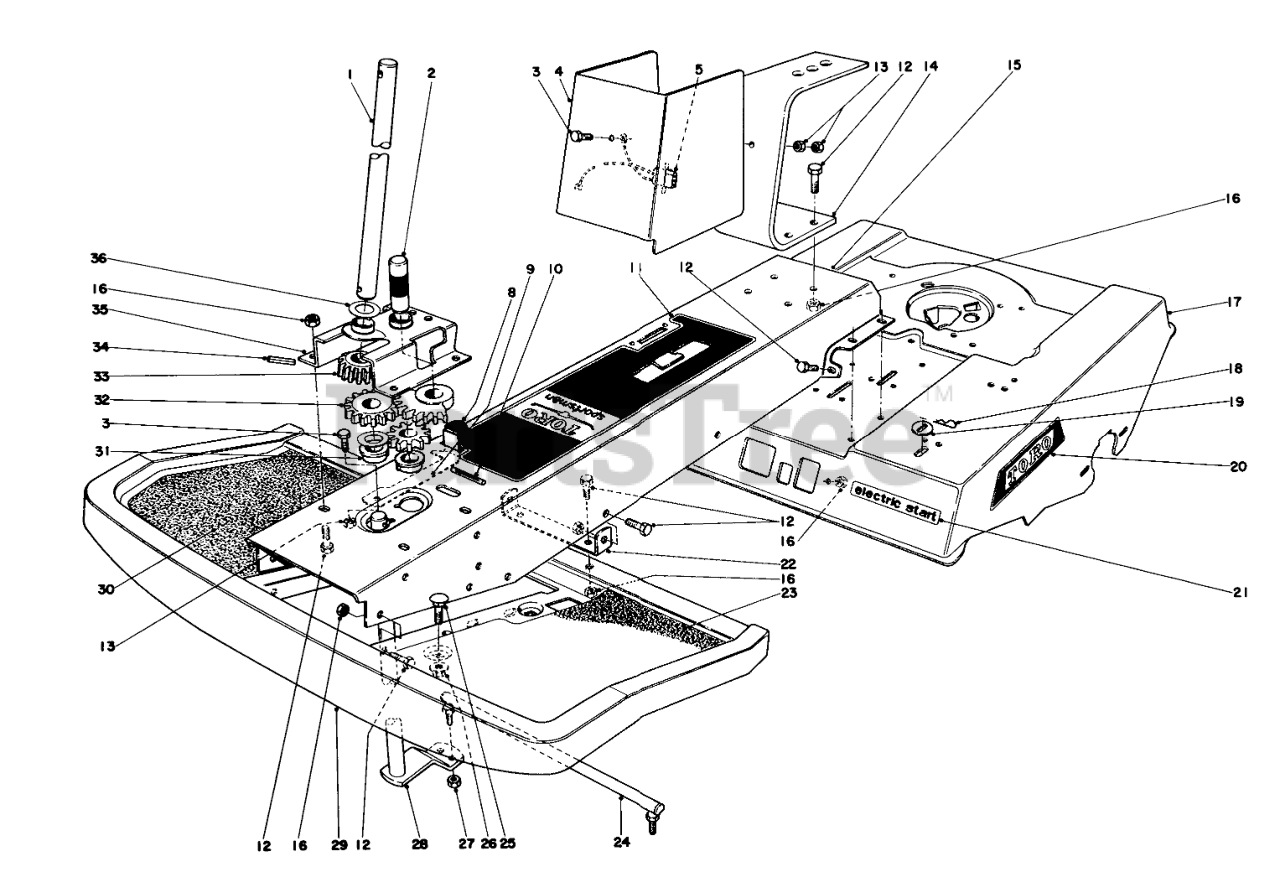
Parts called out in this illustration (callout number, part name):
1	Shaft Upper
2	Steering Idler Ass-y.
3	SCREW-HH
4	Cover Seat
5	Wire (Model 56150)
8	Parking Brake Tip
9	Parking Brake Spring
10	Groove Pin
11	Decal (Model 56100)
12	SCREW-HH
13	NUT-LOCK
14	Seat Spring
15	Center Frame
16	Nut
17	Frame
18	PIN-COTTER
19	Washer
20	Decal
21	Decal (Model 56150)
22	Support
23	Foot Pad L. H.
24	Ball Joint
25	SCREW-CARR
26	NUT-HF
27	Nut
28	Shaft
29	Foot Rest
30	Foot Pad R. H.
31	Bushing
33	STEERING PINION
34	PIN-ROLL, SLOTTED
35	Bracket Steering Support
36	Washer
